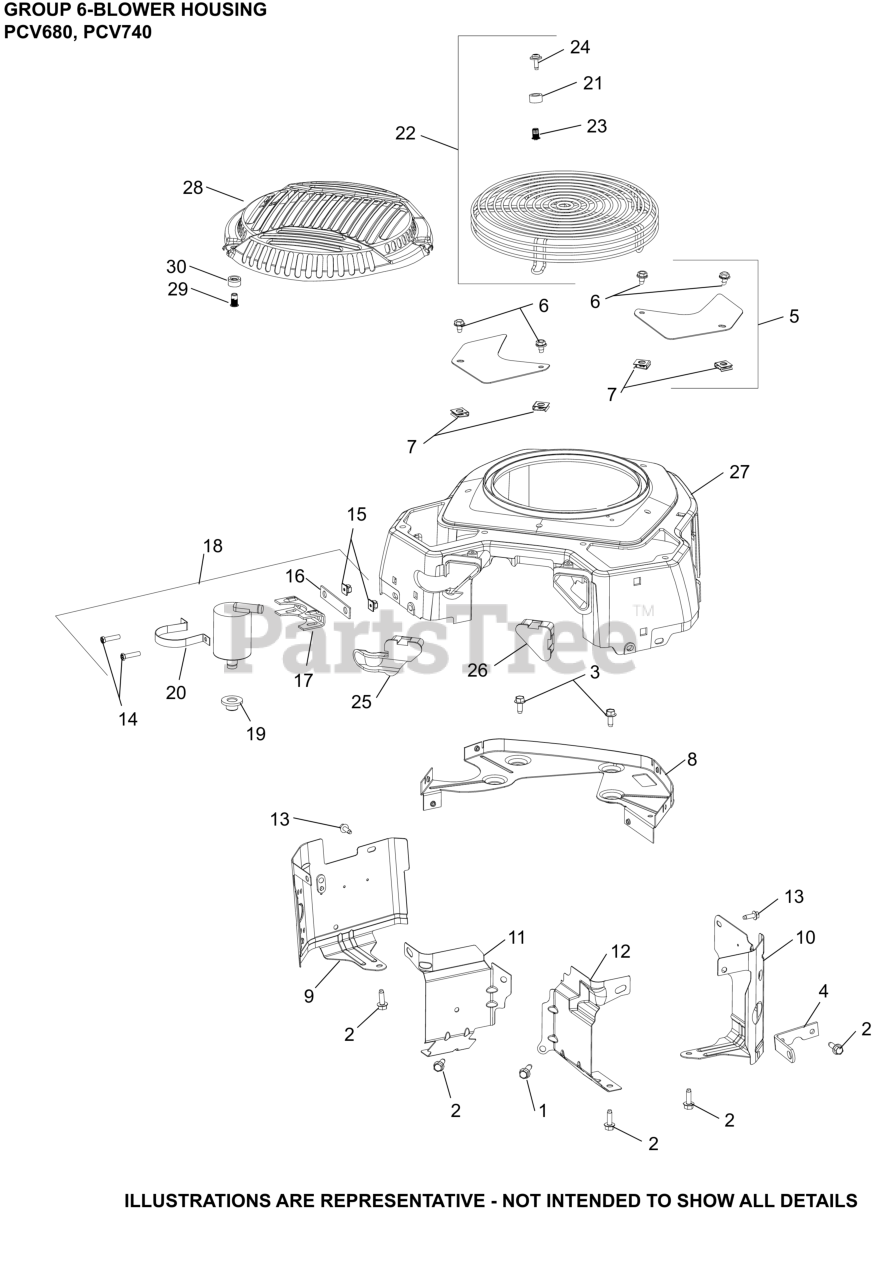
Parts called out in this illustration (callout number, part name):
3	SCREW, THREAD FORMING
4	STRAP, LIFT
5	KIT, ACCESS PANEL
6	SCREW, THREAD FORMING
7	CLIP, BAFFLE MOUNTING
8	PLATE, BACKING
8	KIT, BACKING PLATE
9	KIT, RIGHT BARREL
10	BAFFLE LEFT BARREL
12	BAFFLE, VALLEY #2 CYLINDER
13	SCREW, THREAD FORMING
24	SCREW, SEMS
25	COVER, BLOWER HOUSING
26	COVER, BLOWER HOUSING
28	GUARD, GRASS SCREEN (METAL)
29	INSERT, THREADED (M5)
NI	BAFFLE, VALLEY #1 CYLINDER
